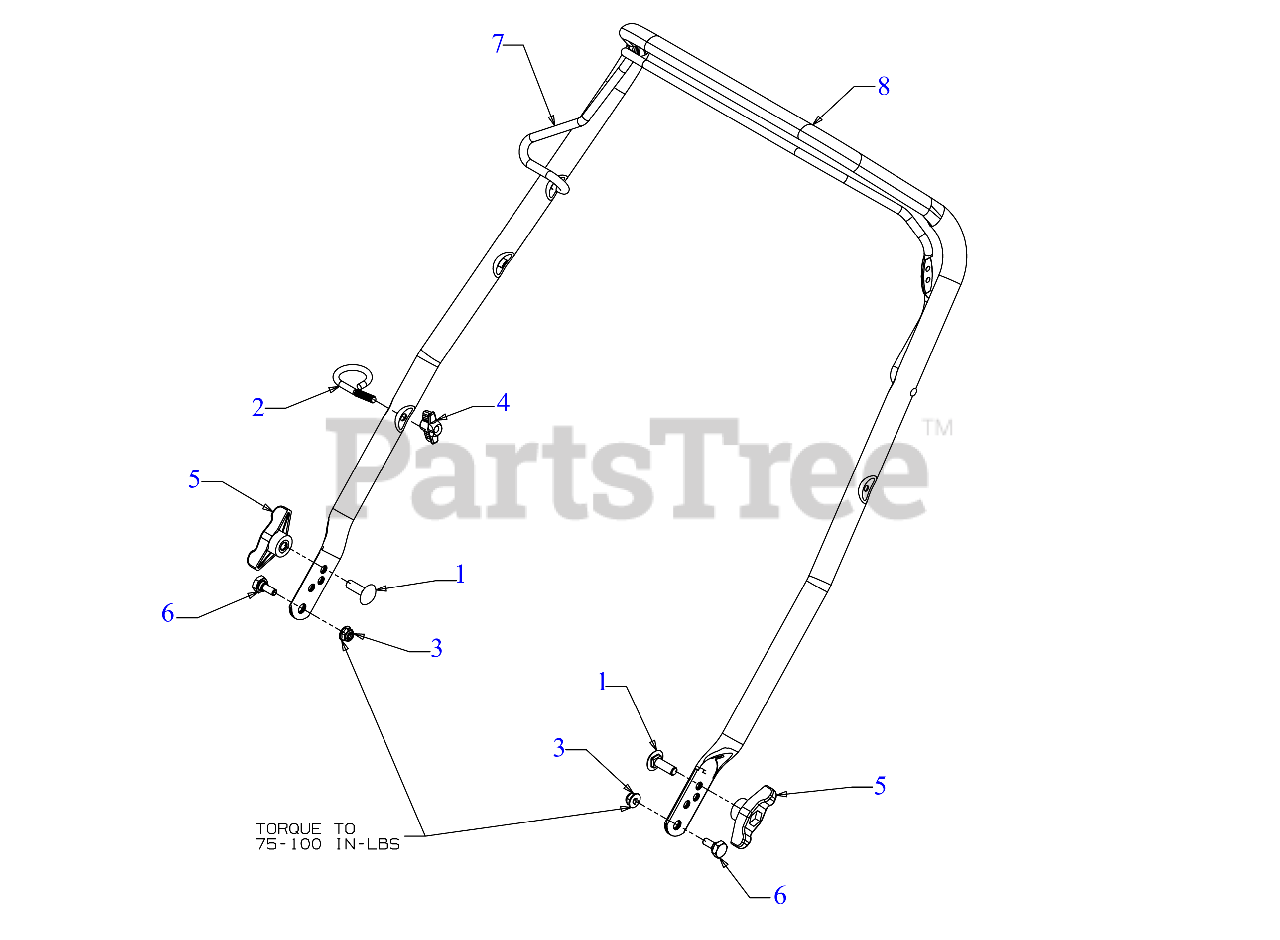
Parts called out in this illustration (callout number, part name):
1	SCREW 5/16-18 x 1.00 GR5
2	EYEBOLT 1/4-20
3	FLANGE LOCK NUT
4	HANDLE KNOB
5	WING KNOB 5/16-18
6	SHOULDER SCREW
